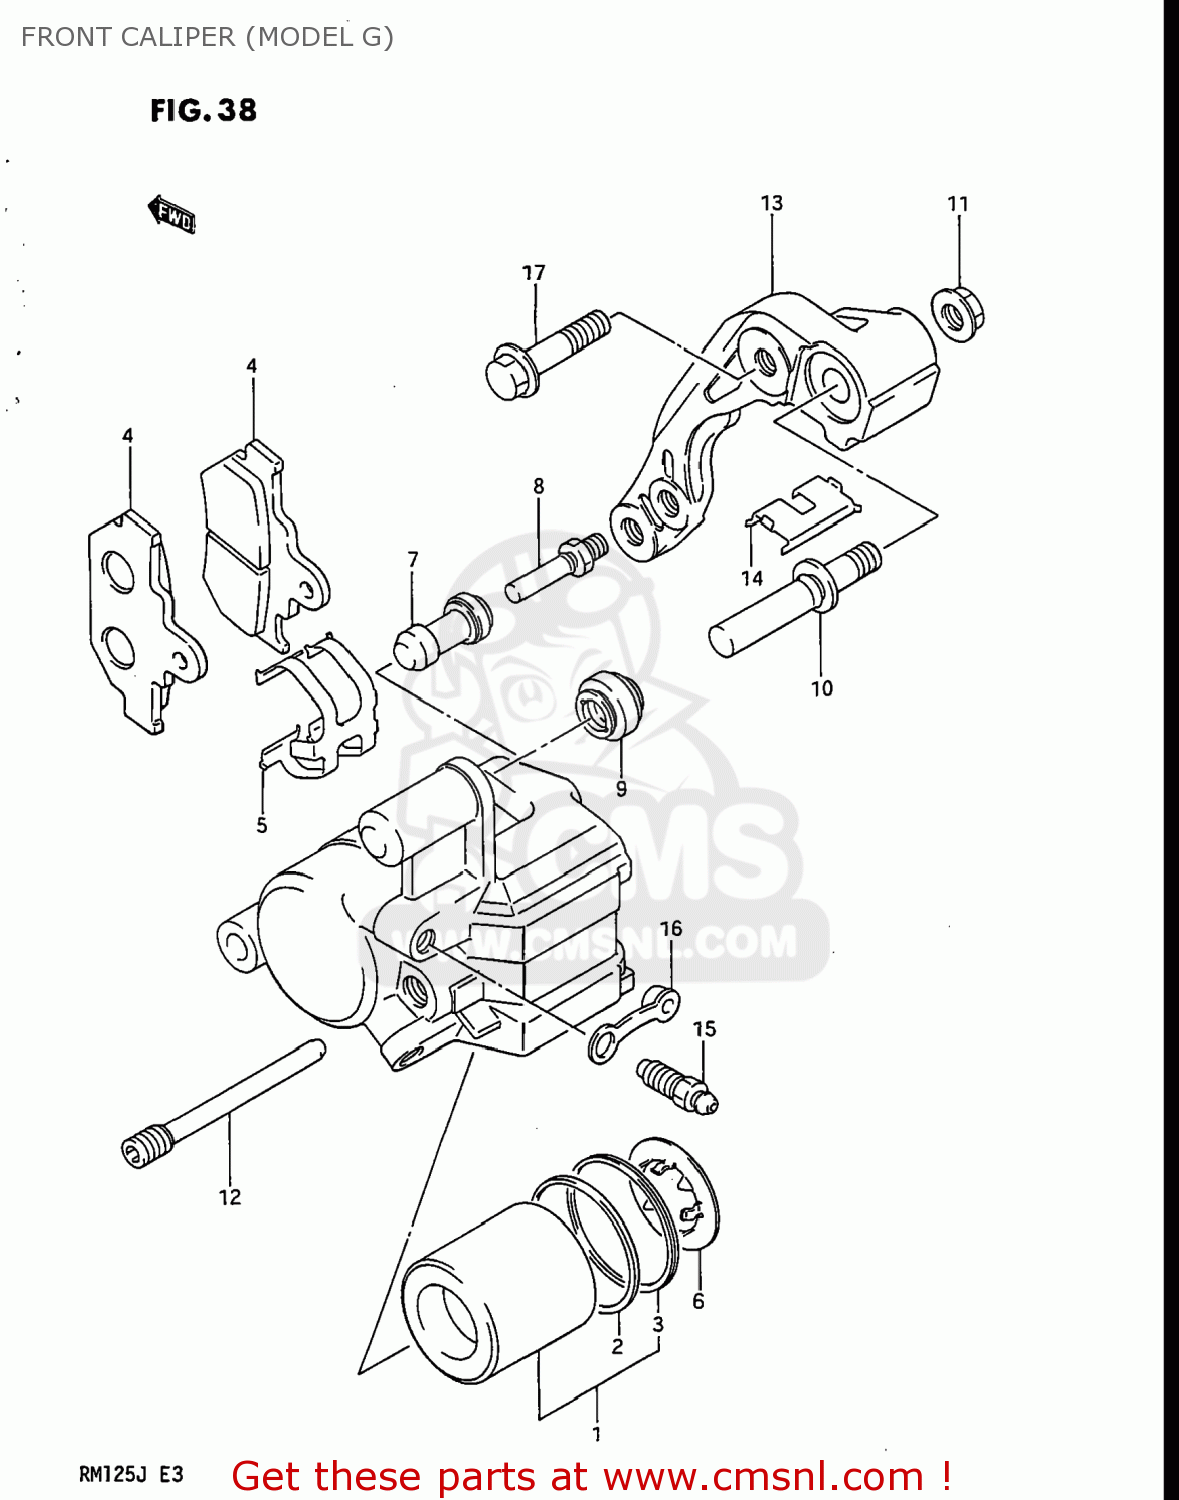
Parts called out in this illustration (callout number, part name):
1	PISTON SET,CALIPERS
2	SEAL,PISTON
3	DUST SEAL,PISTON
4	PAD
5	SPRING
6	SHIM
7	BOOT
8	PIN,BOLT
9	BOOT
10	PIN,SLIDE
11	NUT,SLIDE PIN
12	PIN,HANGER
13	BRACKET
14	RETAINER
15	BLEEDER
16	CAP,BLEEDER
17	BOLT
